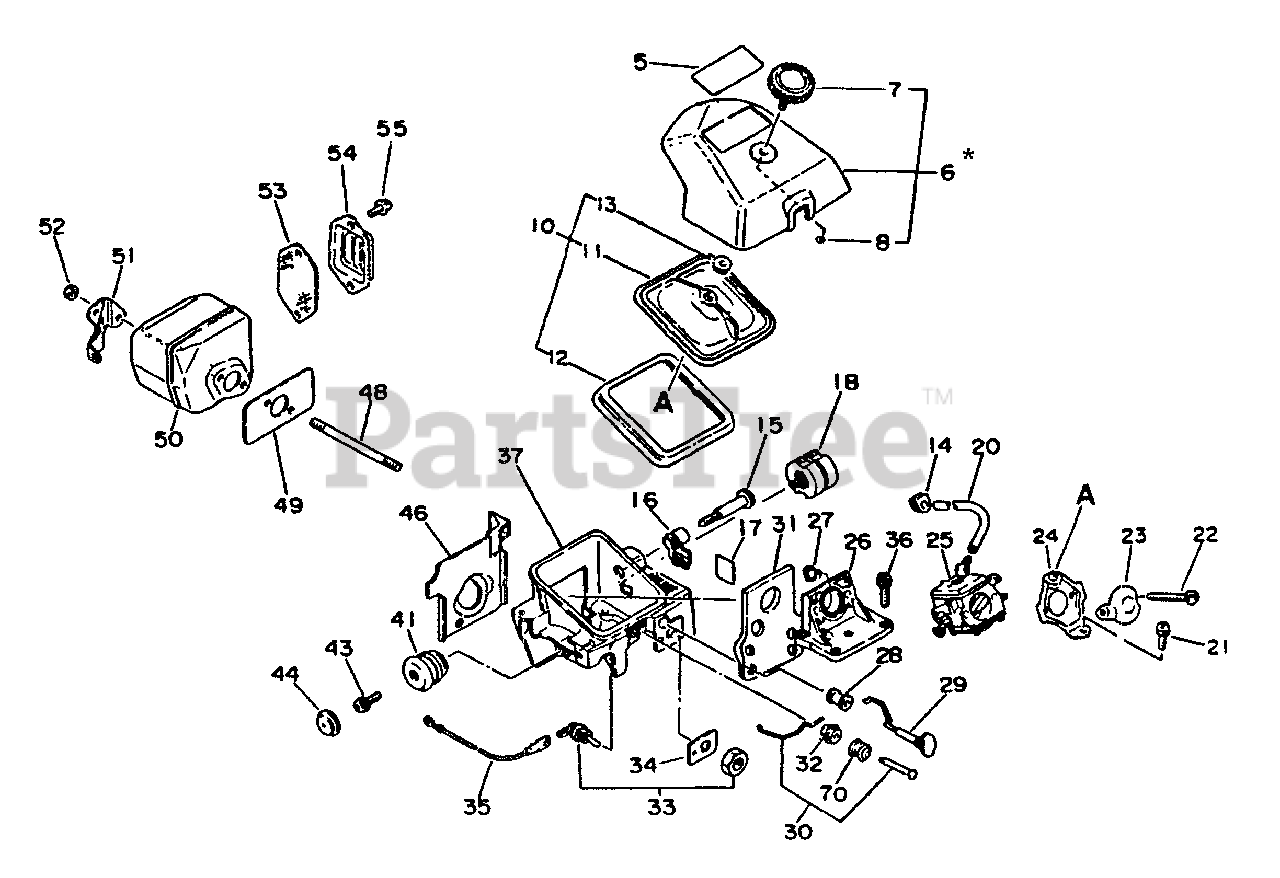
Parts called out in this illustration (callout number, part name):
5	LABEL - MODEL
6	AIR FILTER COVER ASSY
7	THUMBSCREW
8	O-RING - 3
10	AIR FILTER COVER ASSY
11	FILTER, AIR
12	SEAL
14	BUSHING
15	SCREW, IDLE ADJUST
20	PIPE - IMPULSE
21	SCREW - 5X14
22	SCREW - 5X55
23	PLATE, PREVENT
24	BRACKET, AIR CLEANER
25	CARBURETOR
26	INSULATOR, INTAKE
27	NUT
29	ROD, CHOKE
30	ROD, THROTTLE
31	SEAL
32	GUIDE, THROTTLE ROD
33	IGNITION SWITCH ASSY
34	LABEL - STOP
35	LEAD - GROUND
36	SCREW - 5X25
37	CASE, CARBURETOR
41	CUSHION
43	SCREW - 5X10
44	CAP, CUSHION
46	INSULATOR
48	STUD
49	GASKET, EXHAUST
50	MUFFLER
52	LOCKNUT - 5
53	SCREEN, SPARK ARRESTOR
54	LID, MUFFLER
55	SCREW - 4X8
